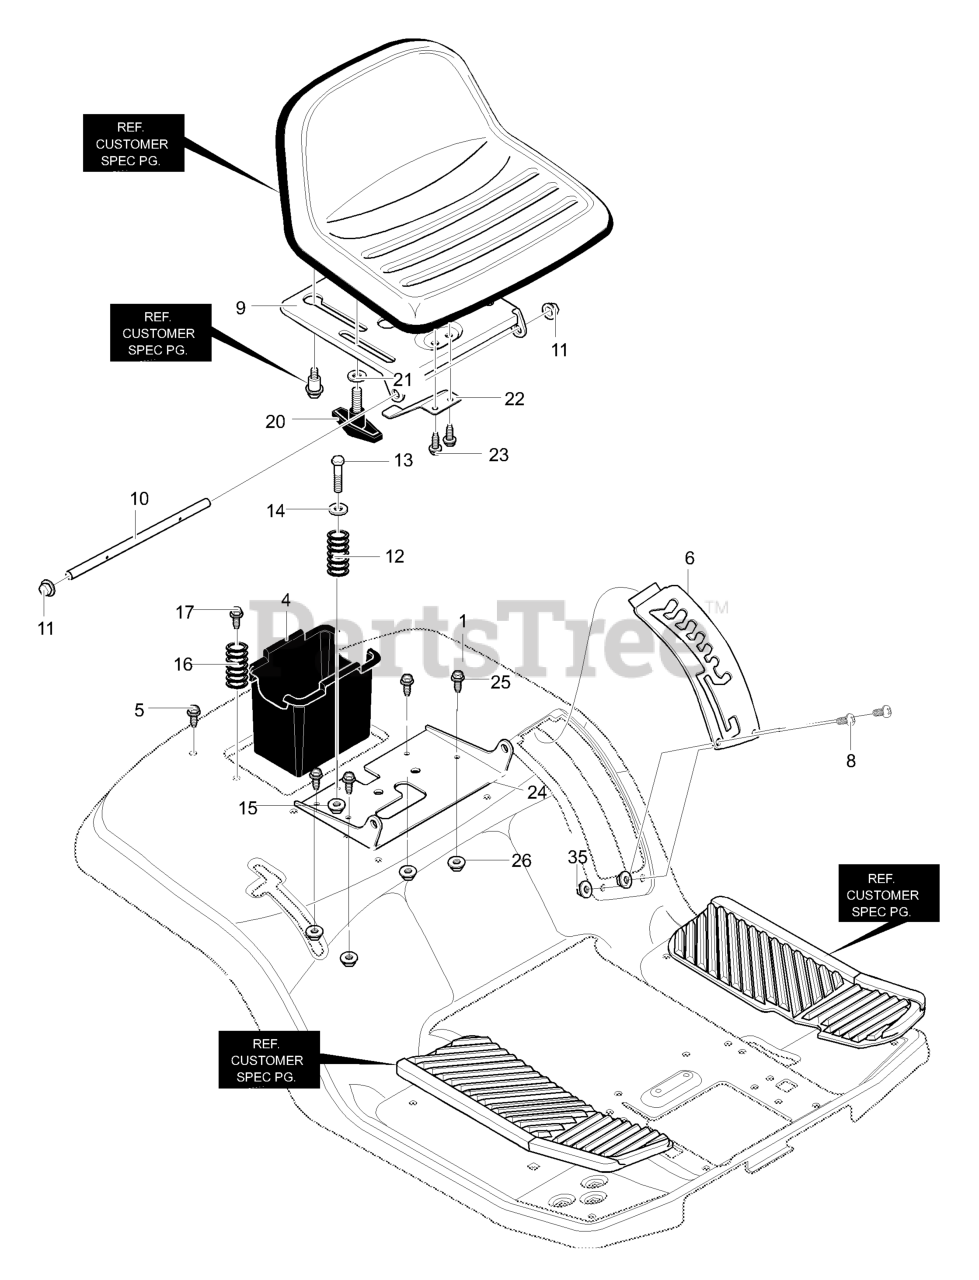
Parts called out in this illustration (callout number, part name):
1	Seat Deck, Small
4	Battery Container
5	Screw, 1/4-20x.63
6	Plate, Lift Detent
8	Screw, 10-24x.500
9	Seat Support
10	Hinge Seat Pivot
11	Push Cap Nut
12	Comp. Spring
13	Shoulder Bolt, 1/4-20
14	Washer Cup
15	Nut, 1/4-20
16	Comp. Spring
17	Screw, 5/16-18 x 0.75
20	Wing Bolt 5/16-18x.50
21	Flat washer
22	Spring - Leaf
23	Screw, 1/4-20x.50
24	Pivot Seat Bracket
25	Screw, 5/16-18 x 0.75
26	Nut, 5/16-18 Wdfllk
35	Nut, #10-24 Locknut
